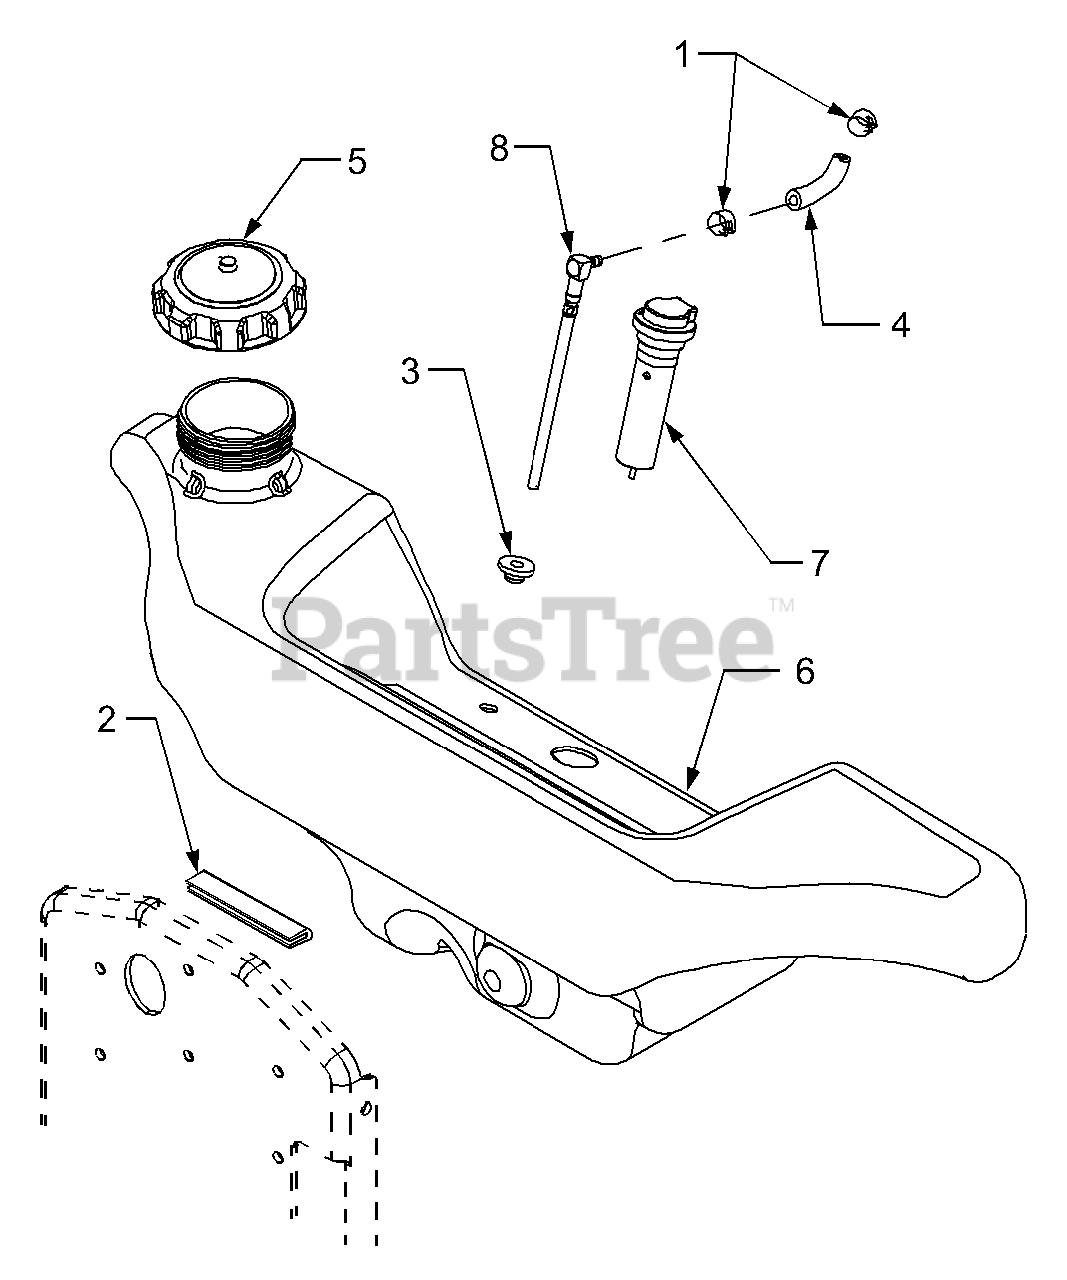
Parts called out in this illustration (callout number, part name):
1	Clamp, Hose
2	Trim, Tank Protector
3	Bushing, Rubber
4	Fuel Line
5	Cap, Fuel
6	Tank, Fuel, 4.5 Gallon
7	Sensor, Low Fuel
8	Fitting, Fuel Pickup
